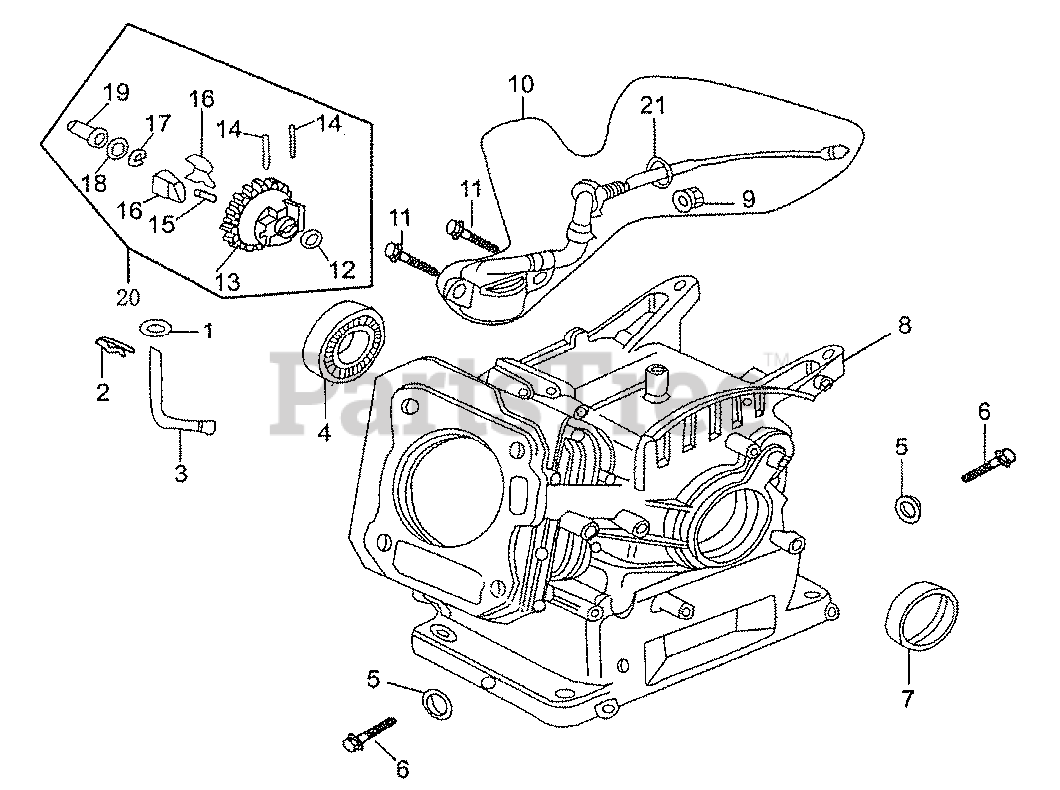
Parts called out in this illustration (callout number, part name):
1	WASHER, PLAIN 0.5MM(1MM)
2	PIN,LOCK,8MM
3	SHAFT,GOVERNOR ARM
4	BEARING BALL RADIAL 6205
5	WASHER,DRAIN PLUG 10.2MM
6	BOLT, DRAIN PLUG 10 X 15
7	OIL SEAL 25X41.25X6
8	CRANKCASE
10	SWITCH ASSY, OIL LEVEL
11	BOLT, FLANGE, 6 X 16
12	WASHER, THRUST 6MM
13	HOLDER, GOV WEIGHT
14	PIN,GOV.WEIGHT
15	REGULATING SHAFT
16	WEIGHT, GOVERNOR
17	CLIP,GOV.HOLDER
18	WASHER,PLAIN 1MM(0.5MM)
19	SLIDER, GOVERNOR
20	GOVERNOR ASSY(4.0g)
21	O-RING, 14MM
